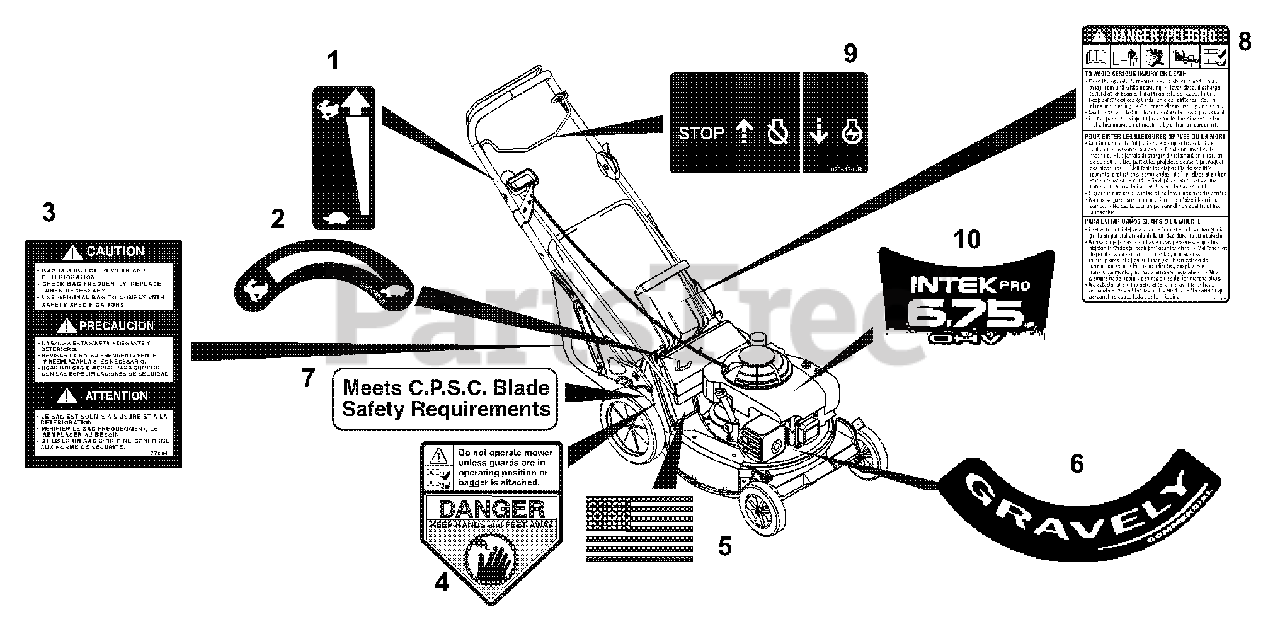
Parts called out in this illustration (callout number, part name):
1	Decal, Speed Control (094, 394)
2	Decal, Turtle and Rabbit (098, 100)
3	Decal, Bagger-21"
4	Decal, CPSC Danger
5	Decal, American Flag
6	Decal, Gravely - Commercial (094, 095, 394)
6	Decal, Gravely - Consumer (098, 100)
7	Decal, C.P.S.C. Blade Safety
8	Decal, Bilingual Danger
9	Decal, Engine Control
10	Decal, Briggs and Stratton Intek 6.75HP (098, 100)
